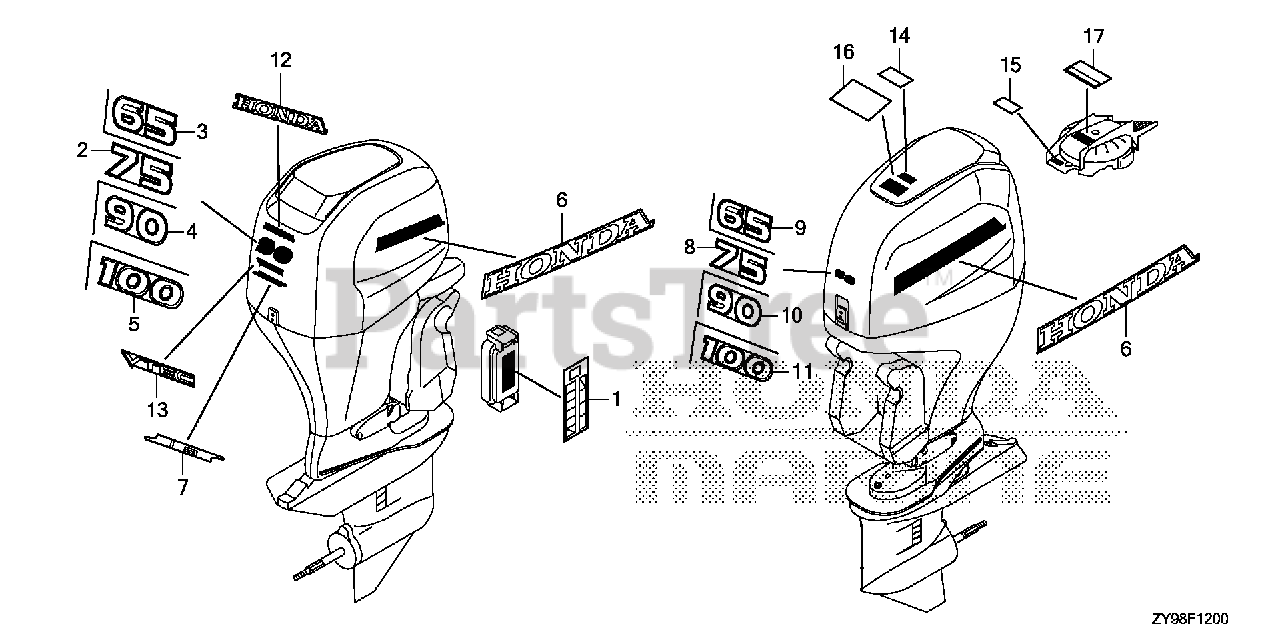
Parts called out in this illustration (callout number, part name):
1	LABEL, FUSE
5	MARK, RR. (100)
6	MARK, SIDE STRIPE
11	MARK, FR. EMBLEM (100)
12	MARK, HONDA
13	MARK (VTEC)
15	LABEL, OIL CAUTION (ENGLISH)
16	LABEL, WARNING OPERATOR (ENGLISH)
17	MARK, EMERGENCY START (ENGLISH)
